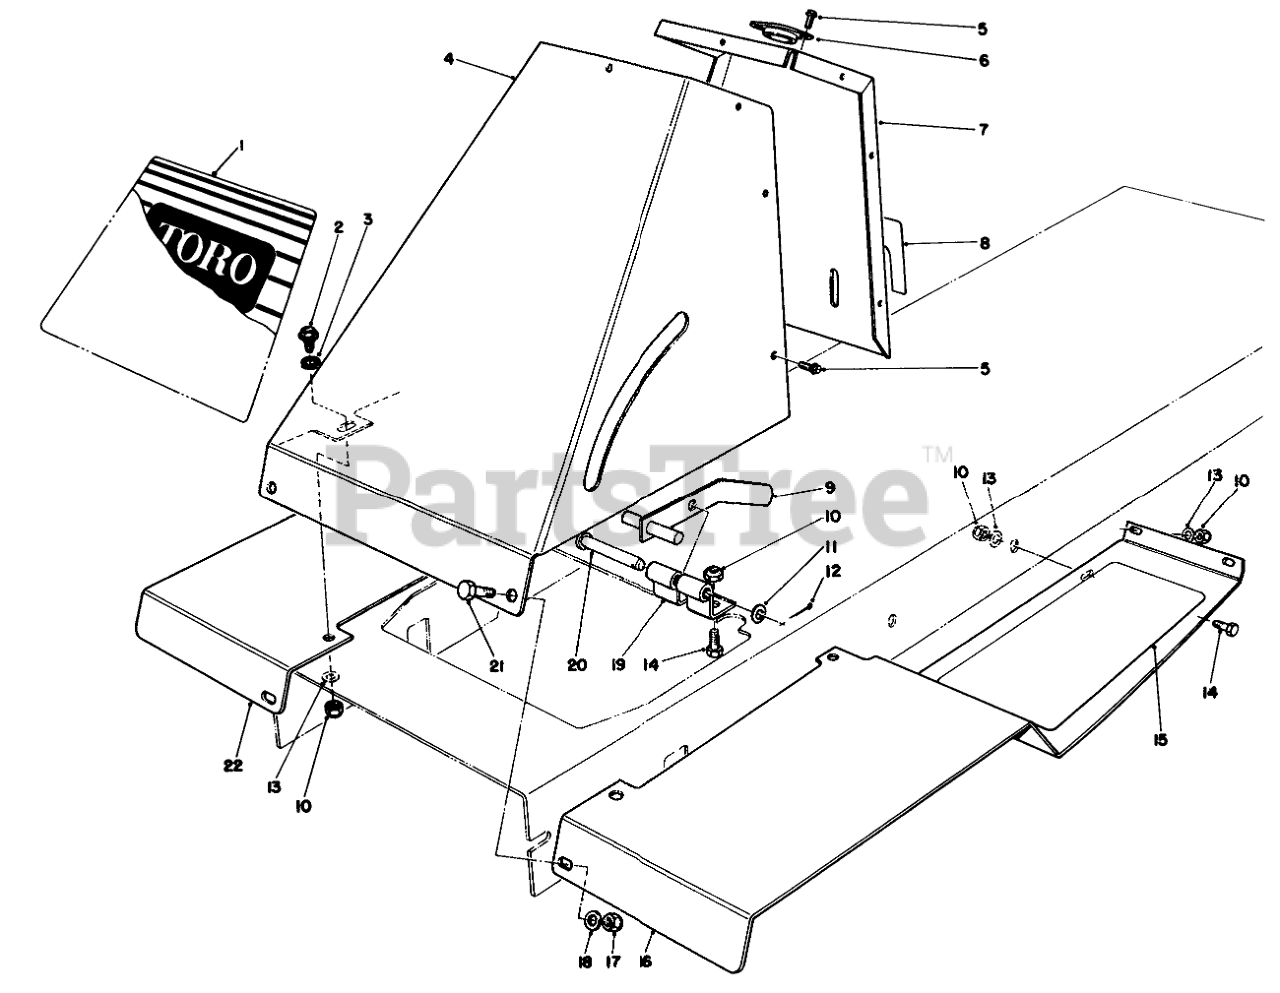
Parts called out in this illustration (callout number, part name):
1	Decal-Toro 8-32
2	SCREW-SHOULDER
3	SPACER
4	Tower-Front
5	SCREW-HWHTF
6	GUIDE-STRG SHAFT
7	Tower-Rear
8	PARK BRAKE DECAL
9	PARKING BRAKE WA B
10	NUT-LOCK, NI
11	WASHER-FLAT
12	PIN-COTTER
13	WASHER-PLAIN
14	SCREW-HH
15	FOOT TREAD L.H.
16	Footrest-LH
17	NUT-LOCK, CONE
18	WASHER-FLAT
19	Bracket-Parking Brake
20	PIN-CLEVIS
21	SCREW-HH
22	Footrest-RH.
